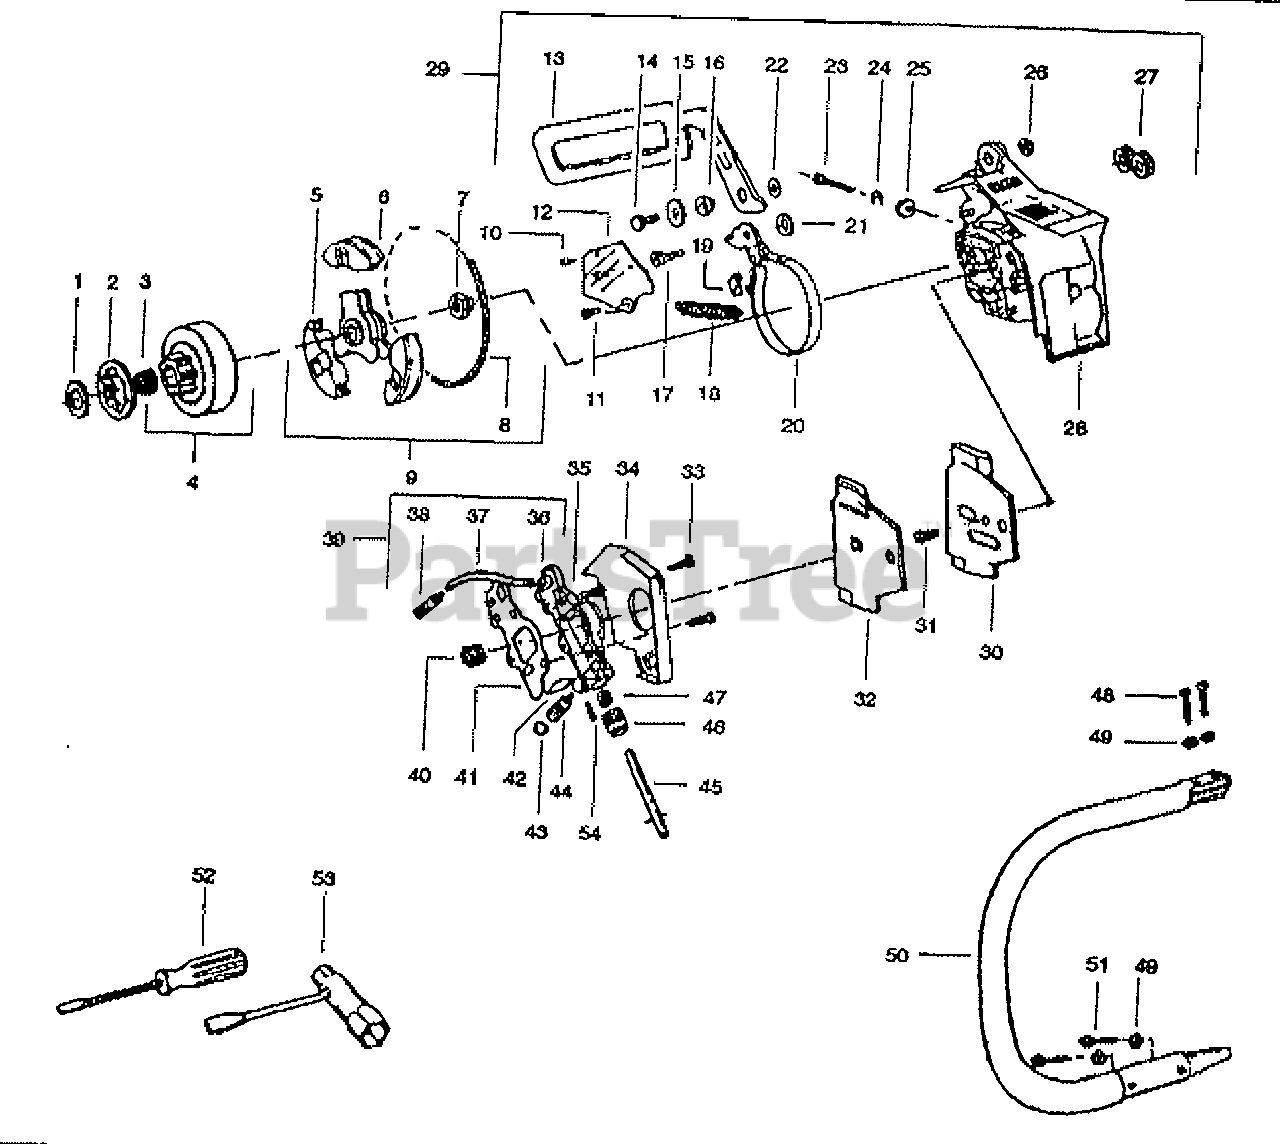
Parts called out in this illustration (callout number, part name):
1	Thrust Washer
2	Rim Spocker (3/0 7 tooth)
4	Clutch Drum
5	Clutch Shoe
6	Clutch Driver
8	Clutch Spring
9	Clutch Ass'y
13	Kickback Guard Assy.
17	Shoulder Bolt
19	Locking Plate
20	Band Ass'y
24	Retaining Ring
27	Strut Nut
28	Clutch Cover & Tension
29	Chain Brake Ass'y
30	Guide Plate - Outer
31	Terminal Screw
32	Guide Plate - Inner
34	Dirt Shield
36	Oil Pump Ass'y
38	Oil Pickup Ass'y
39	Oil Pickup Ass'y
40	Wire Worm
44	Adjusting Screw
45	Plunger Ass'y
47	Plunger Spring
50	Frong Handle Kit
52	Screwdriver
53	Combination T Wrench
54	Roll Pin
